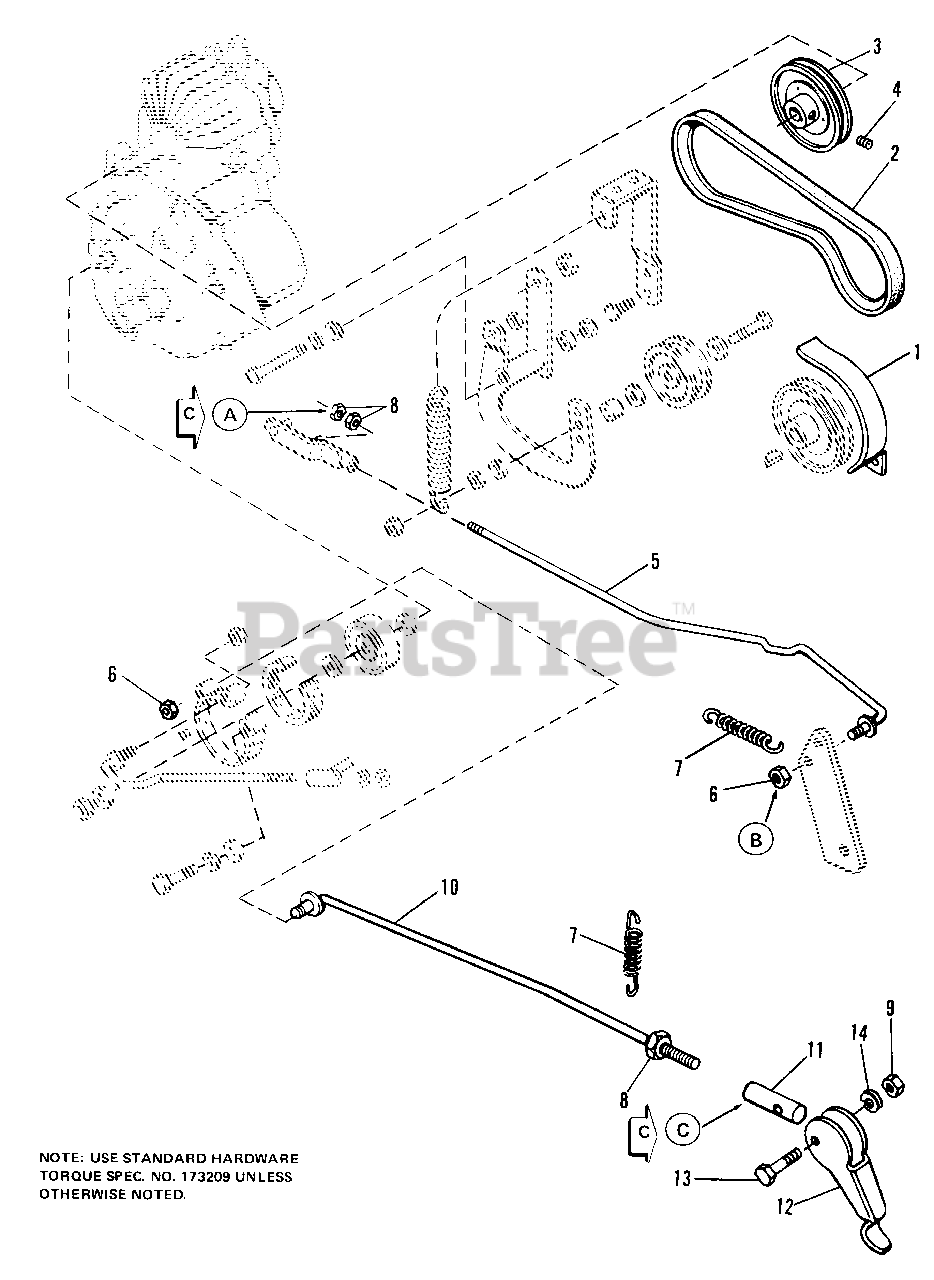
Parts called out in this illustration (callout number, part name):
3	PULLEY
4	SETSCREW, Sq. Hd., 5/16-18 x 3/8
5	ROD, Clutch
6	NUT, Lock, Hex, 5/16-18
8	NUT, Hex, Full, 5/16-18
9	NUT, Lock, Hex, 1/4-20
12	LEVER, Parking Brake
13	CAPSCREW, Hex Hd., 1/4-20 x 1-1/4
14	LOCKWASHER, Dbl. 1/4
